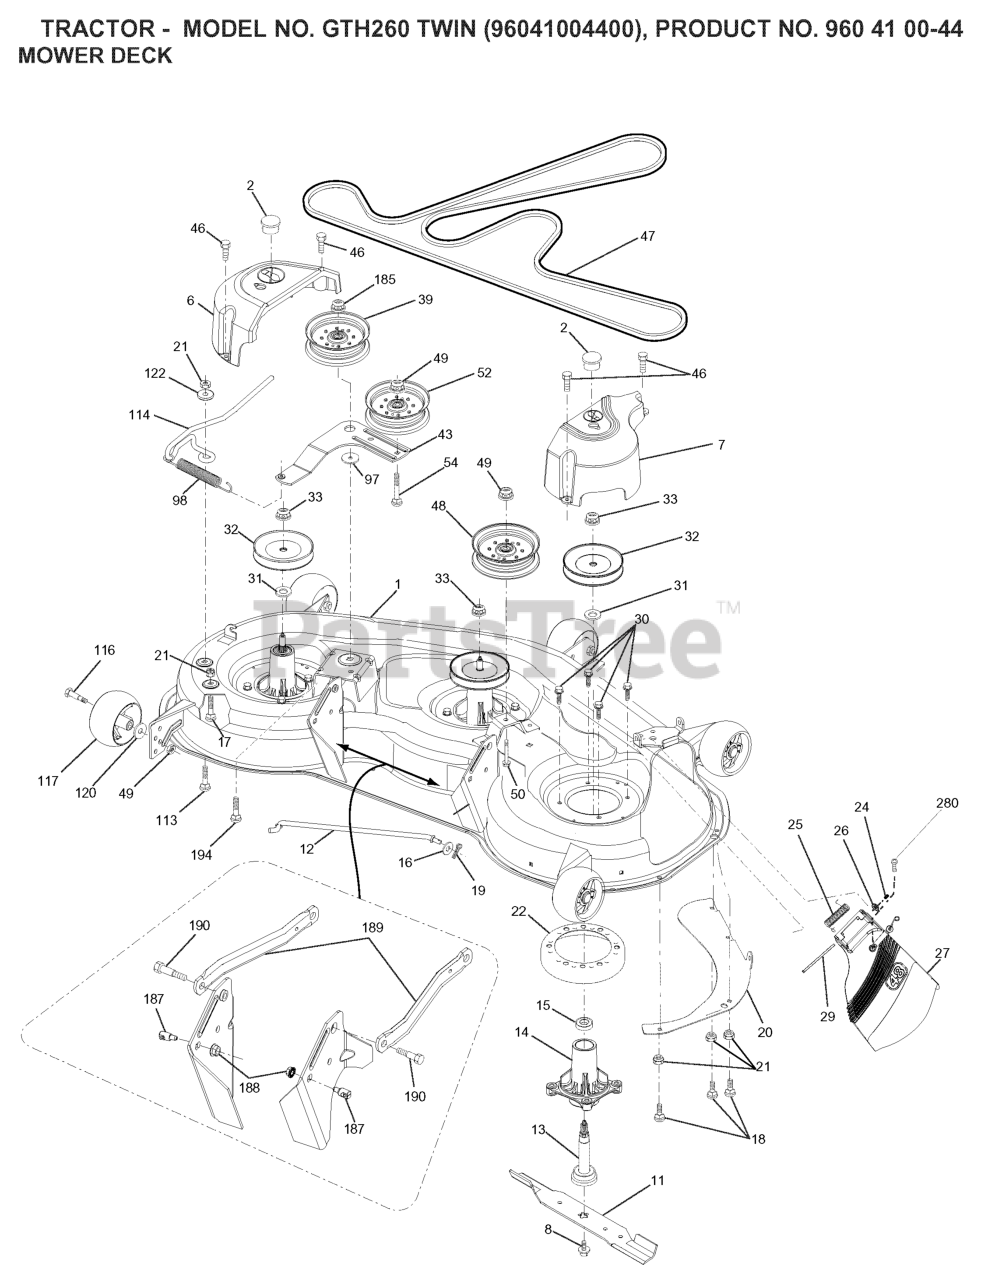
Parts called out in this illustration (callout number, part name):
1	DECK WELDMENT
8	BOLT 7/16 ASM BLADE
11	48" HI-LIFT BLADE
12	ROD.ANTI.SWAY.48/54"TE
13	SHAFT ASM MANDREL
14	RP.HOUSING.MANDREL.4PT.
16	WASHER
17	BOLT.CARR.5/16-18X5/8.SHORT
18	BOLT
19	PIN.COTTER.5/16.BOW TI
20	BAFFLE, VORTEX MWR
21	LOCKNUT
22	STRIPPER.MANDREL.ROUND.BLACK
24	CAP-SLEEVE LT
25	SPRING, TORSION
26	NUT PUSH M
29	ROD.HINGE
30	SCREW, WASHER HEAD
31	WASHER.SPACER.MANDREL
32	PULLEY MANDREL
33	NUT.FLANGE.LOCK.TOP
39	RB PULLEY.IDLER.4.50/HUB SPEC
46	SCREW.1/4-20X5/8
47	BELT.DRIVE.DECK
48	PULLEY.IDLER.48"PRIMARY
49	NUT LOCK FLG 3/8-16 UNC
50	BOLT.3/8-16X1.50
52	PULLEY.IDLER.2006
54	SCREW TT 3/8-16X2-1/4 UNC
98	SPRING, DECK DRIVE
114	ROD.TENSION.RELIEF.TEX (2 2)
116	BOLT.SHOULDER.3/8-16X3-5/8.
117	RP WHEEL. GUAGE RALLY
120	WASHER
122	BUSHING.RELIEF.TENSION
185	NUT.LOCK.FLANGE.7/16
187	STUD.FASTNER.W/ANTI-ROTATE
188	NUT LOCK HEX FLANGE 5/16-18
189	ARM.SUSPENSION.MOWER
190	BOLT.SHOULDER
194	BOLT.CARR.SQNK.7/16
280	SCREW 3/8-16X1/2
